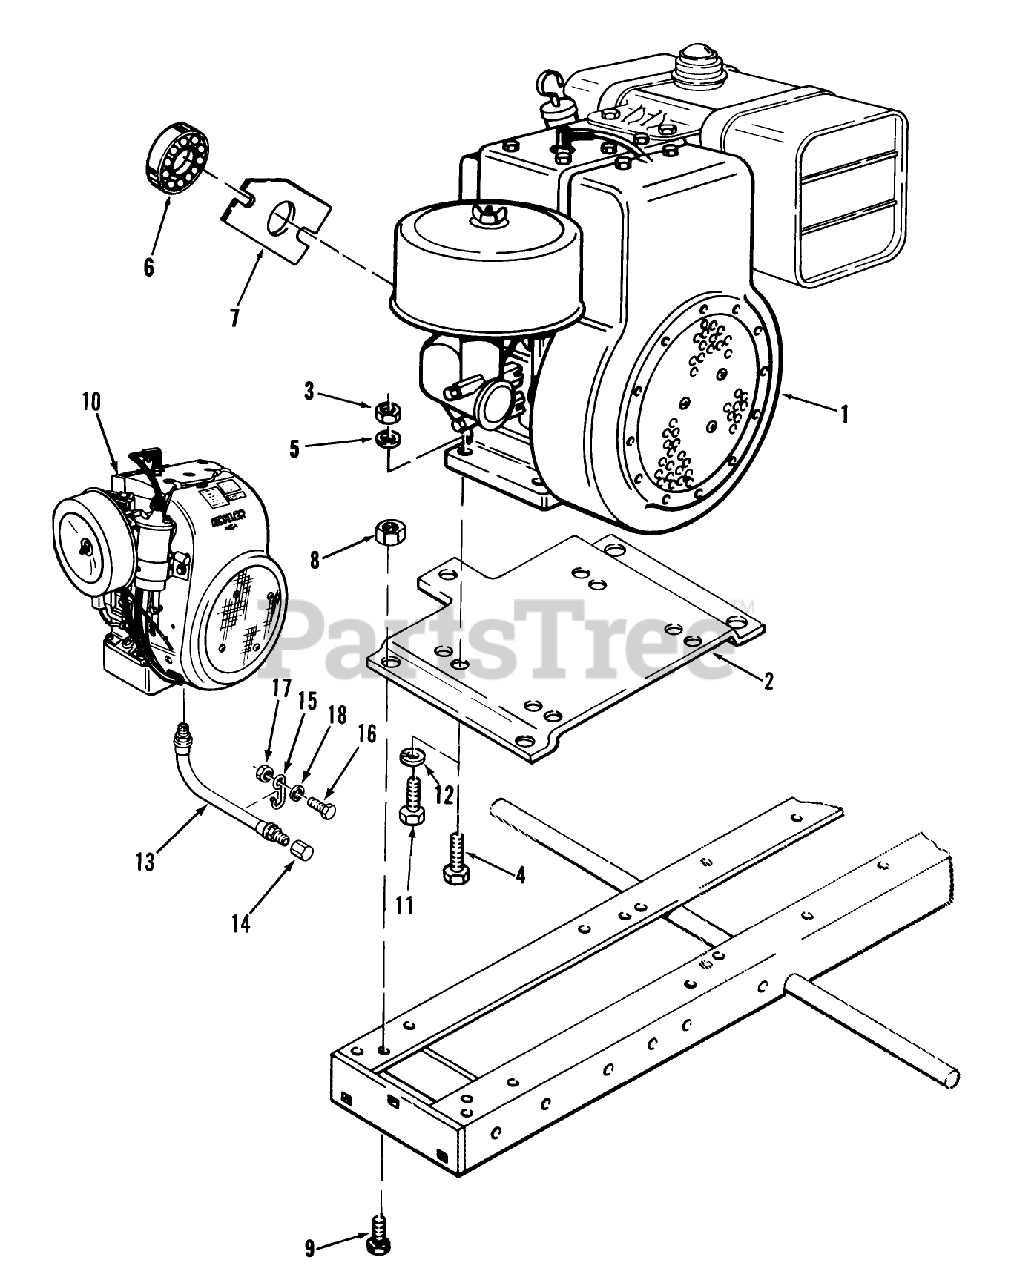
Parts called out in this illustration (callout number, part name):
1	Engine-11 HP Briggs Stratton 252417 Type 0245-01
10	Engine-16 HP Kohler K-341AS Spec 71311
15	RETAINER-HOSE
